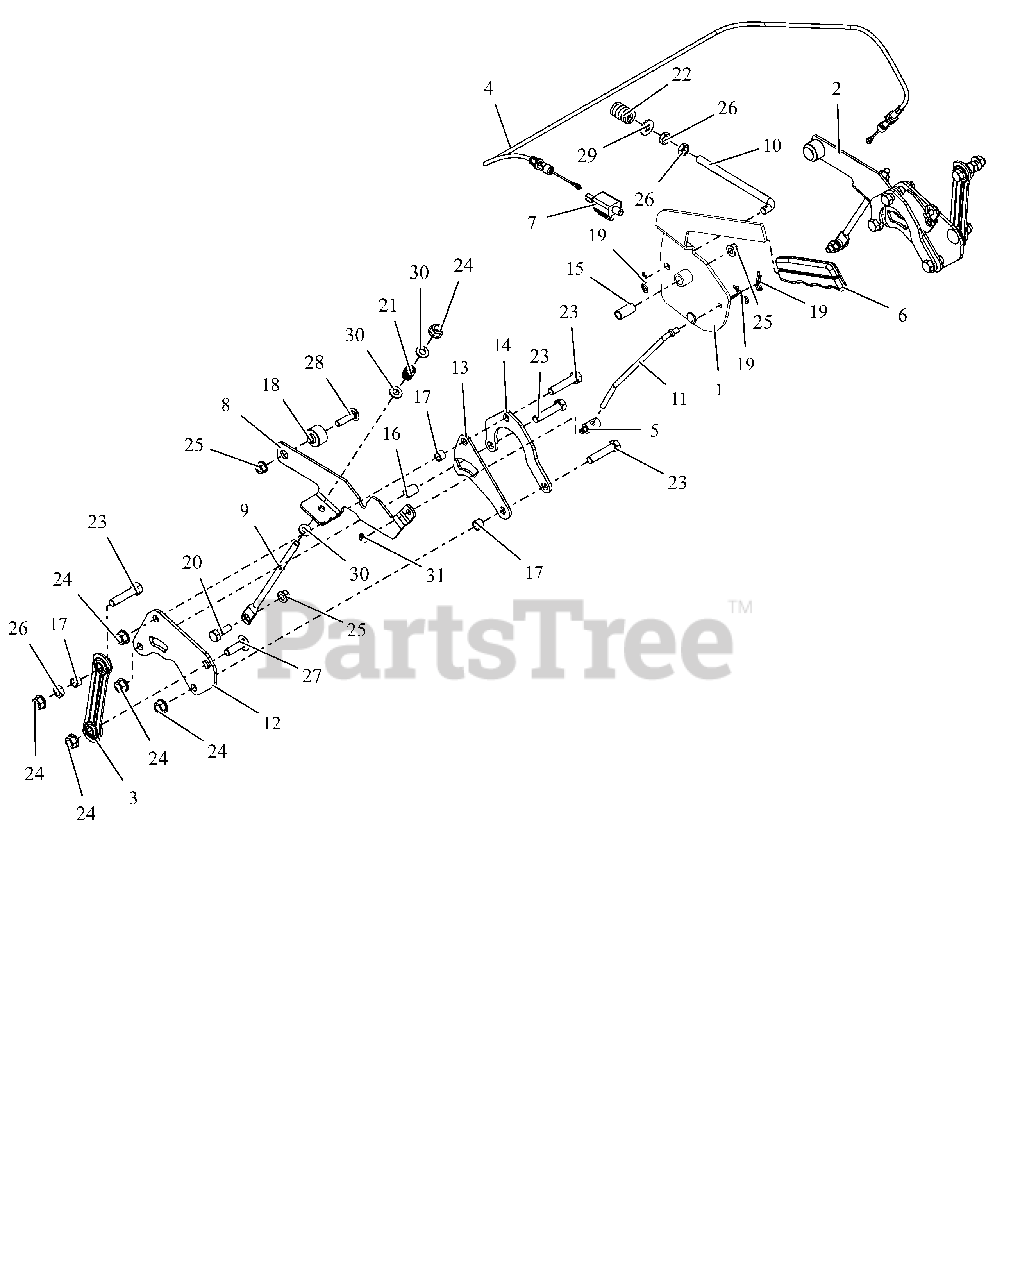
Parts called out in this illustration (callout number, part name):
1	LEVER, PARKING BRAKE
2	ARM, BRAKE - LH (W/PIN)
3	LINK, STAMPED STEERING
4	CABLE, BRAKE
5	TRUNION, 1/4-20
6	GRIP, PARKING BRAKE (YELLOW)
7	SWITCH, SINGLE POLE N.O.
8	ARM, BRAKE-RH
9	ROD, LINK - TRANSMISSION BRAKE
10	ROD, OVER CENTER
11	ROD, BRAKE LINK
12	BRKT, TRANSAXLE STEERING
13	BRKT-SPACER
14	PLATE, REAR REINFORCING
15	BSHG-SLV .385X.500X1.045
16	SPCR, SLV .385X.500X.652
17	SPCR, SLV .385X.500X.350
18	SPCR, FLANGE
19	PIN, HAIR #213 .08X1.19 ZCC
20	BOLT,SHLDR .38X.25 -.31-18X.75
21	SPRING, COMPRESSION
22	SG-COMP .187X.56X1.62
23	BLT, HEX .38-16X1.75 G5 ZCC
24	NUT-LK-TOP-FLG .38-16 ZC120
25	NUT-LK-TOP-FLG .312-18 GF ZCC
26	NUT-JAM .375-16 G2 ZCC
27	BLT,RHSSN .38-16X1.25 G5 ZCC
28	BTL,RHSSN .313-18 X 1.25 G5 ZCC
29	WSHR,FLT .375X.875X.083 ZCC
30	WSHR,FLT .344X.688X.065 ZCC
31	RG-RTNG-EXT .250X.025
